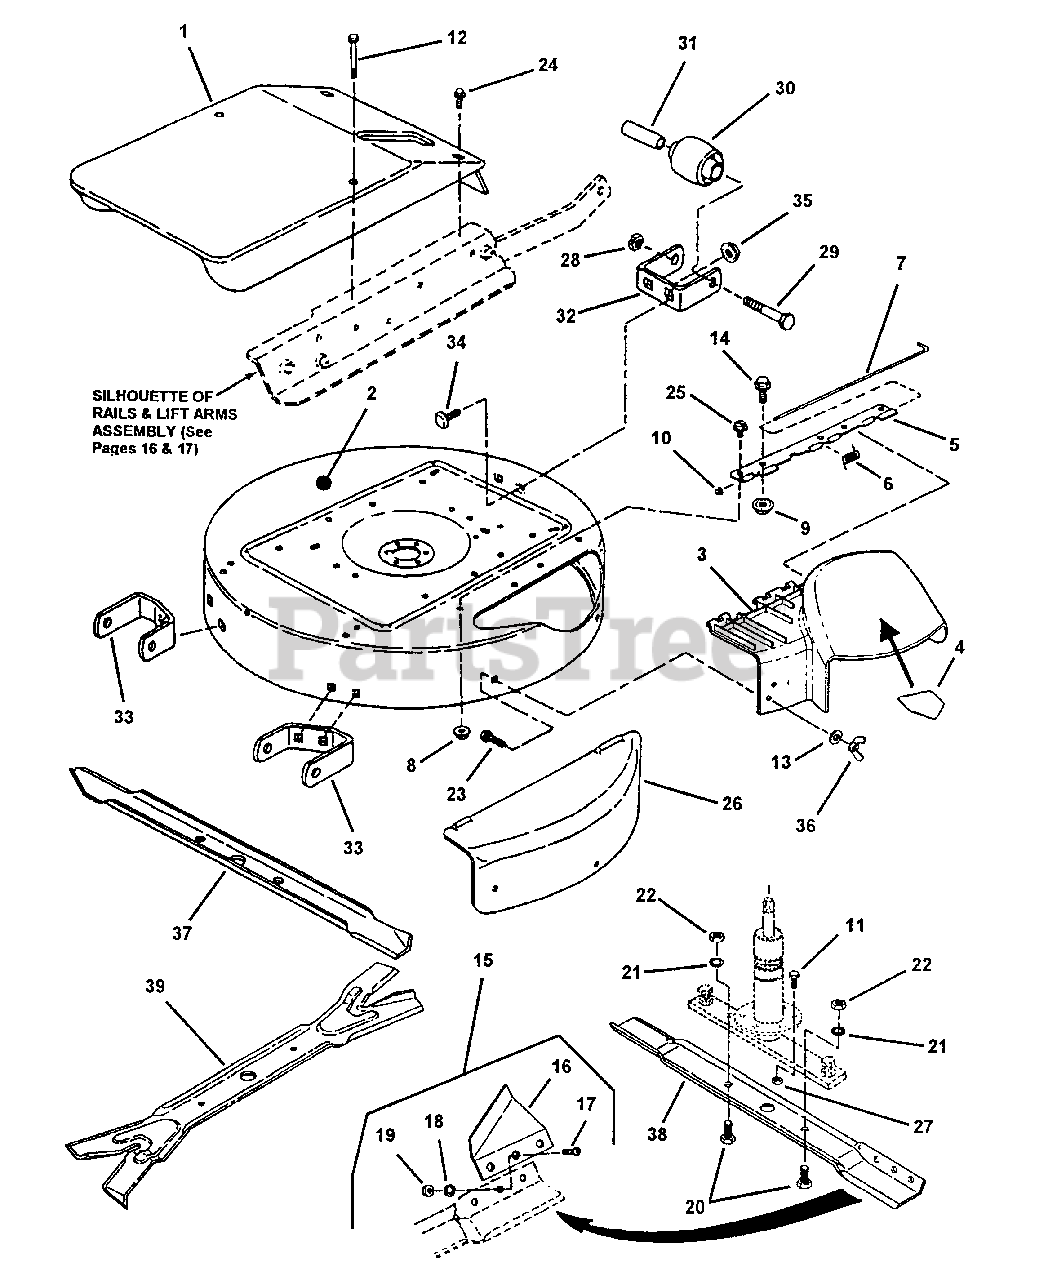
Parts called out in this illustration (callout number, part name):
1	COVER, Spindle
2	DECK, 28" Replacement (Painted deck with decals)
2	DECK, 33" Replacement (Painted deck with decals)
3	DEFLECTOR, Discharge (28" & 33" Deck)
4	DECAL, DANGER (Cut Finger)
5	HINGE, Deflector
6	SPRING, Hinge
7	PIN, Hinge
8	NUT, 5/16-18 Hex Flange Lock
9	NUT, 1/4-20 Hex Flange Lock
10	NUT, Push
11	BOLT, 3/8-16 x 3/4" Hex Flange Lock
12	SCREW, 1/4-20 x 3-1/2" Hex Washer Self-Tap, Gr. 5
13	WASHER, 5/16 Flat
14	BOLT, 1/4-20 x 1/2" Hex Flange Lock
15	AIR LIFT KIT, Hi-Vac
16	AIR LIFT, Hi-Vac (3 hole)
17	SCREW, 5/16-24 x 11/16" Machine
18	WASHER, 5/16-24 Internal Tooth Lock
19	NUT, 5/16-24 Hex
20	SCREW, 1/2-20 x 1" Hex Head Cap, Grade 5
21	WASHER, 1/2 Internal Tooth Lock
22	NUT, 1/2-20 Hex Jam
23	BOLT, 5/16-18 x 3/4" Short Neck Carriage, Grade 5
24	SCREW, 1/4-20 x 5/8" Hex Self-Tap w/ Captured Washer
25	BOLT, 5/16-18 x 1/2" Hex Flange Lock
26	COVER, 28" Mulcher
26	COVER, 33" Mulcher
27	NUT, 3/18-16 Hex Flange Lock
28	NUT, 3/8-24 Hex Nyloc
29	SCREW, 38-24 x 3-3/4" Hex Head Cap, Grade 5
30	WHEEL, Gage
31	SPACER
32	BRACKET, Gage Wheel (Front)
33	BRACKET, Gage Wheel (Rear)
34	BOLT, 5/16-18 x 1/2" Short Neck Carriage, Grade 5
35	NUT, 5/16-18 Hex Flange Lock
36	NUT, 5/16-18 Wing
37	BLADE, 28" Mulcher
37	BLADE, 33" Mulcher
38	28" BLADE (3 Air Lift Holes)
38	33" BLADE (3 Air Lift Holes)
39	BLADE, Ninja, 28"
39	BLADE, Ninja, 33"
